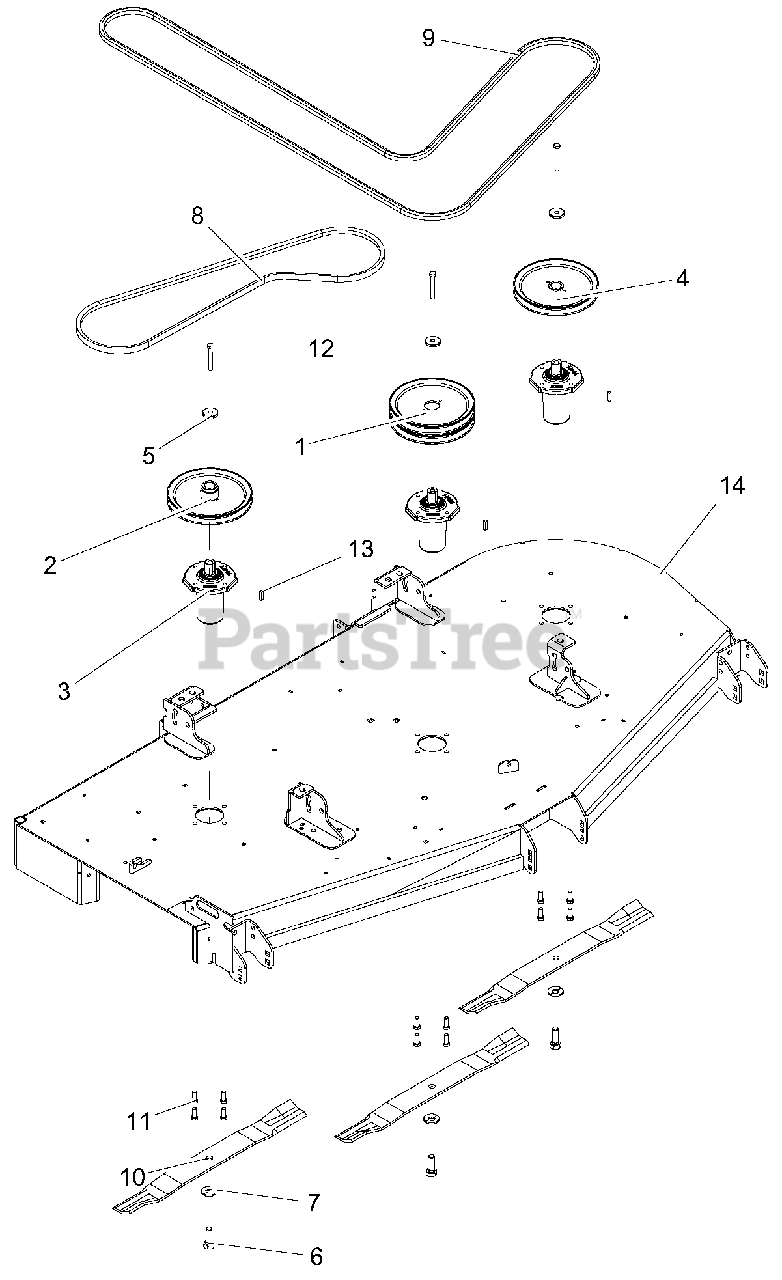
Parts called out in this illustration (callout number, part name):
1	SHEAVE-DOUBLE 1.00"ID X 8.25"OD-BLACK
2	SHEAVE, SINGLE 1.00" ID X 8.25" OD-BLACK
3	SERVICE, ASM SPINDLE- DUCTILE
4	SHEAVE-SINGLE 1.00" X 8.25" OD-BLACK
5	RETAINER, SHEAVE SPINDLE
6	BLT, HEX .62-18X1.75 GR8 YWZC
7	WSHR, BLVL .63X1.625X.14
8	V-BELT, B-COGGED
9	HEX BELT, BB-WRAPED
10	BLADE, MOWER 72" (24.5" LG)
11	BLT-HEX .38-16X1.00 GR5 YWZC EP30
12	BLT-HEX .38-16X2.75 GR8 YWZC
13	KEY-SQ .250X.250X1.00 RC 40-50
14	72" SIDE DISCH DECK W/ DECALS
